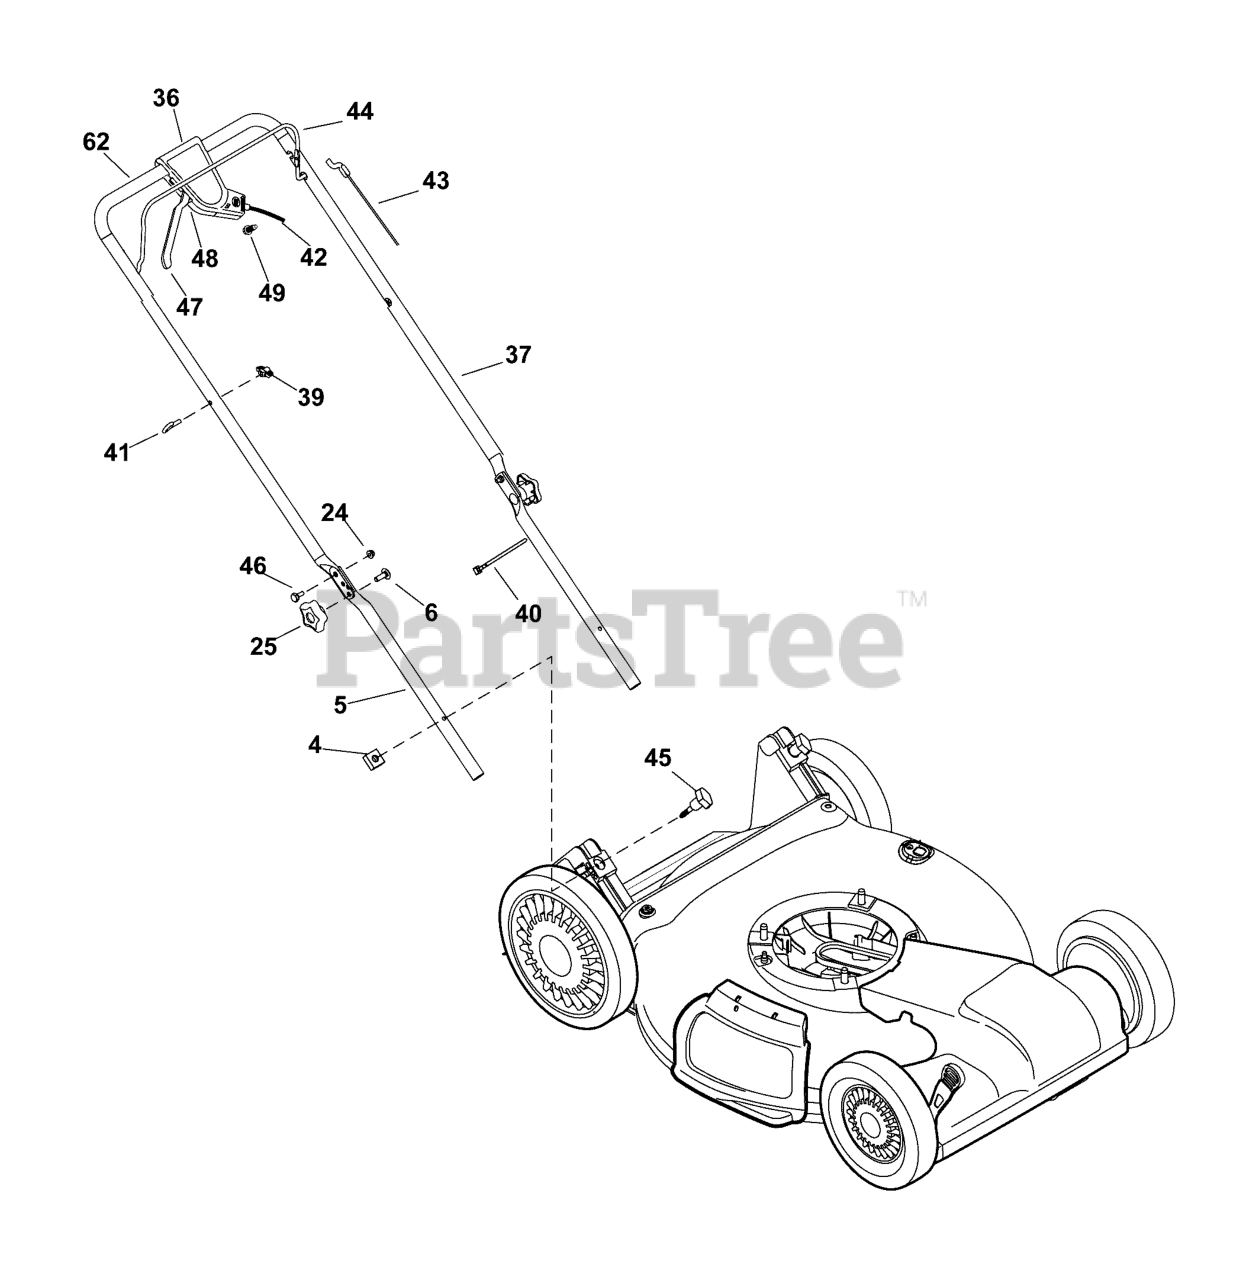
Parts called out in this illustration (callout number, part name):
4	NUT, Square, 1/4-20
5	HANDLE, Lower
6	BOLT, Carriage, 5/16-18 x 1, GR5
24	NUT, Flange Nylock , 1/4-20
25	KNOB, Wing, 5/16-18
36	ASSEMBLY, Control Lever
37	HANDLE, Upper
39	KNOB, 1/4-20
40	TIE, Self Lock
41	GUIDE, Rope
42	CABLE, Control
43	CABLE, OPC Engine Brake
44	CONTROL, Bail
45	NUT, Wing
46	BOLT, Shoulder, 1/4-20
47	LEVER, Control
48	COVER, Control Lower
49	SCREW
